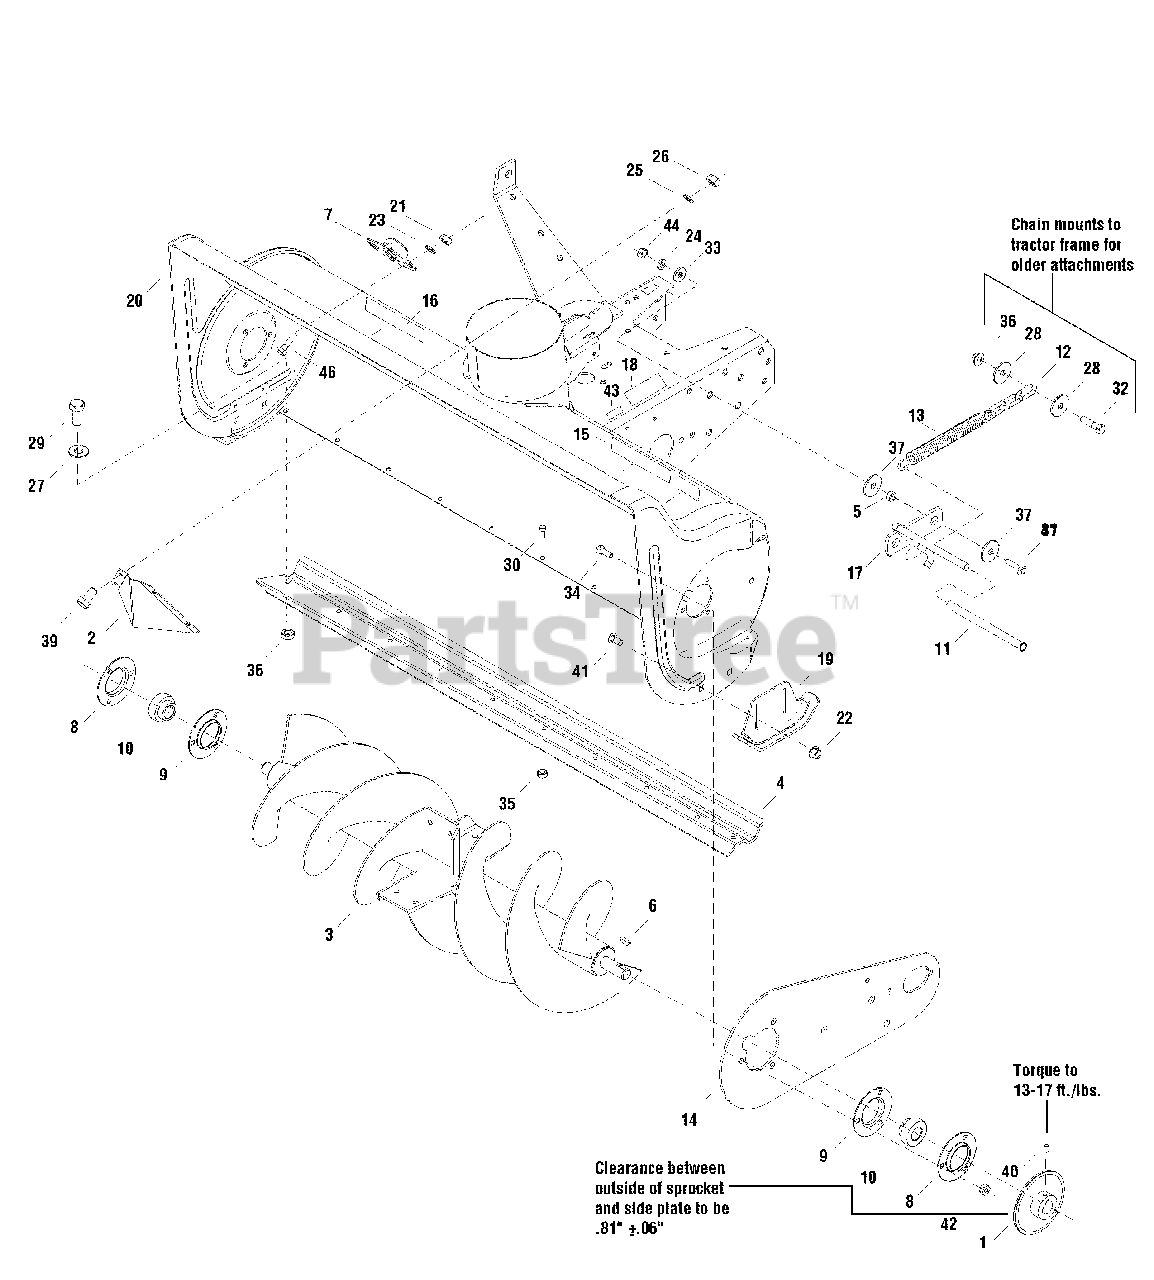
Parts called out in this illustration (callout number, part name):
1	SPROCKET, Rotor, 29 Tooth
3	ROTOR ASSEMBLY
4	SCRAPER, Body
8	FLANGE, Bearing
9	FLANGE, Bearing
10	BEARING, Cartridge
14	PLATE, Side
15	DECAL, Safety
16	DECAL, Safety
17	LEVER ASSEMBLY
18	DECAL, Caution
19	SKID, w/ Wear Strip
20	BODY & FRAME ASSEMBLY
21	NUT, Hex, 1/4-20
22	NUT, ESNA Hex, 3/8-16
23	LOCKWASHER, 1/4
24	LOCKWASHER, 3/8
25	LOCKWASHER, 5/16
26	NUT, 5/16-18
27	WASHER, 11/32
28	WASHER, 5/16
29	CAPSCREW, Hex Head, 5/16-18 x 3/4
30	CAPSCREW, Hex Head, 1/4-20 x 5/8
31	CAPSCREW, Hex Head, 3/8-16 x 1-1/2
32	CAPSCREW, Hex Head, 5/16-18 x 1-1/4
33	WASHER, 3/8
34	CAPSCREW, Hex Head, 5/16-18 x 7/8
35	LOCKNUT, Hex, 1 /4-20
36	LOCKNUT, Hex, 5/16-18
37	WASHER, 3/8
39	CAPSCREW, Hex Head, 5/16-18 x 5/8
40	SETSCREW, 5/16-18 x 5/16
41	CARRIAGE BOLT, 3/8-16 x 3/4
42	NUT, Hex, Flange Lock, 5/16-18
43	DECAL, I. D.
44	NUT, Hex, Full 3/8-16
46	CAPSCREW, HexHead, 1/4-20 x 1
